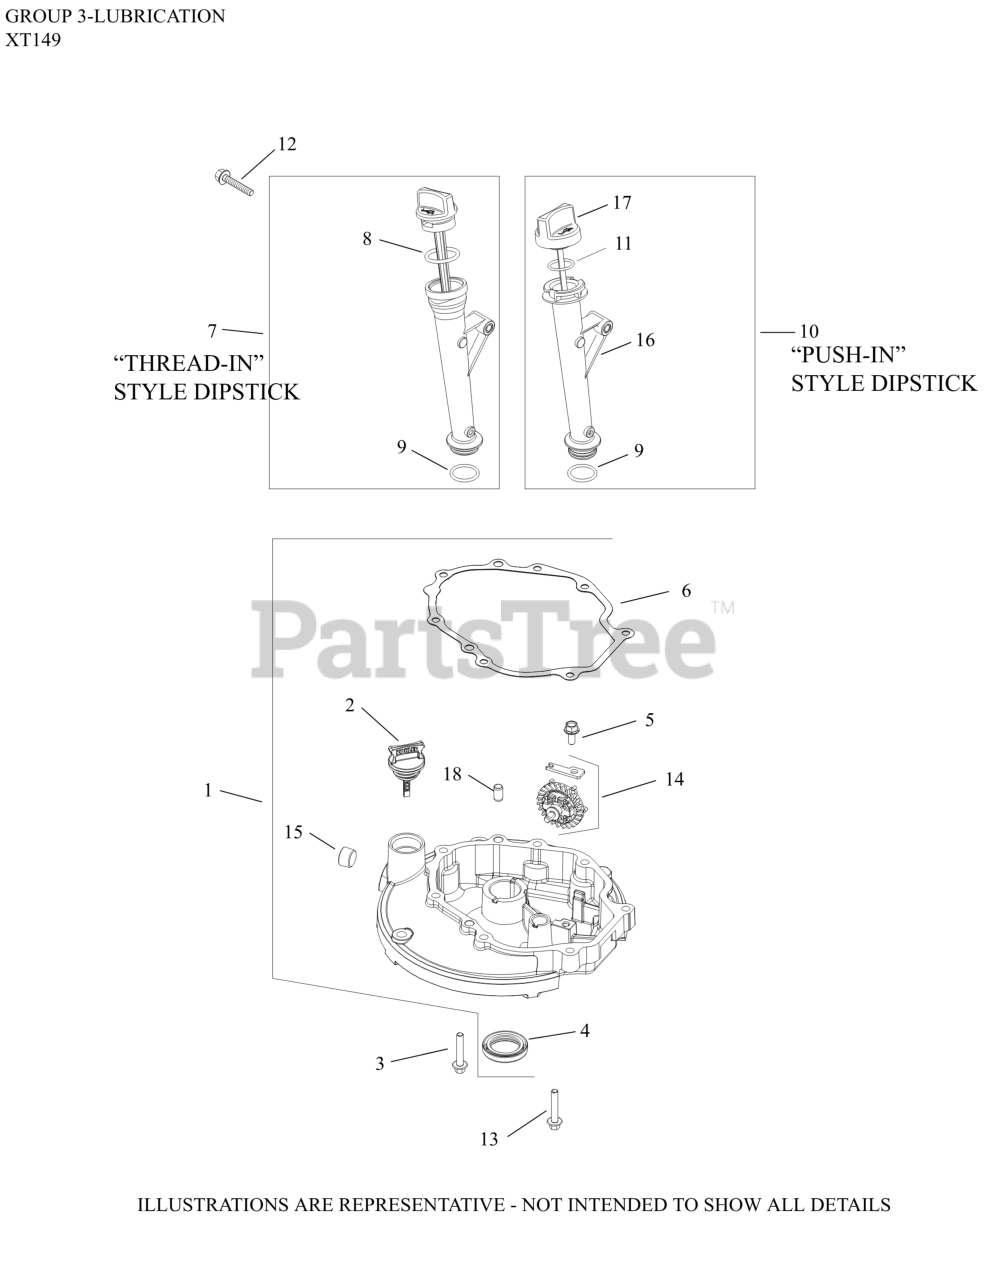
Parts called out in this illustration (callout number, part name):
1	KIT, OIL PAN
6	GASKET, OIL PAN
9	O-RING, OIL FILL TUBE
10	KIT, DIPSTICK AND TUBE-(#1412320S)
11	O-RING (CAP)
12	SCREW, HEX FLANGE (M6)-(#25086435S)
13	SCREW, HEX FLANGE (M6)-(#25086434S)
14	GEAR ASSEMBLY, GOVERNOR
15	PLUG, PIPE (W/SEALANT)
16	TUBE ASSEMBLY, OIL FILL
17	CAP, DIPSTICK ASSEMBLY
18	PIN, DOWEL (8MM)
